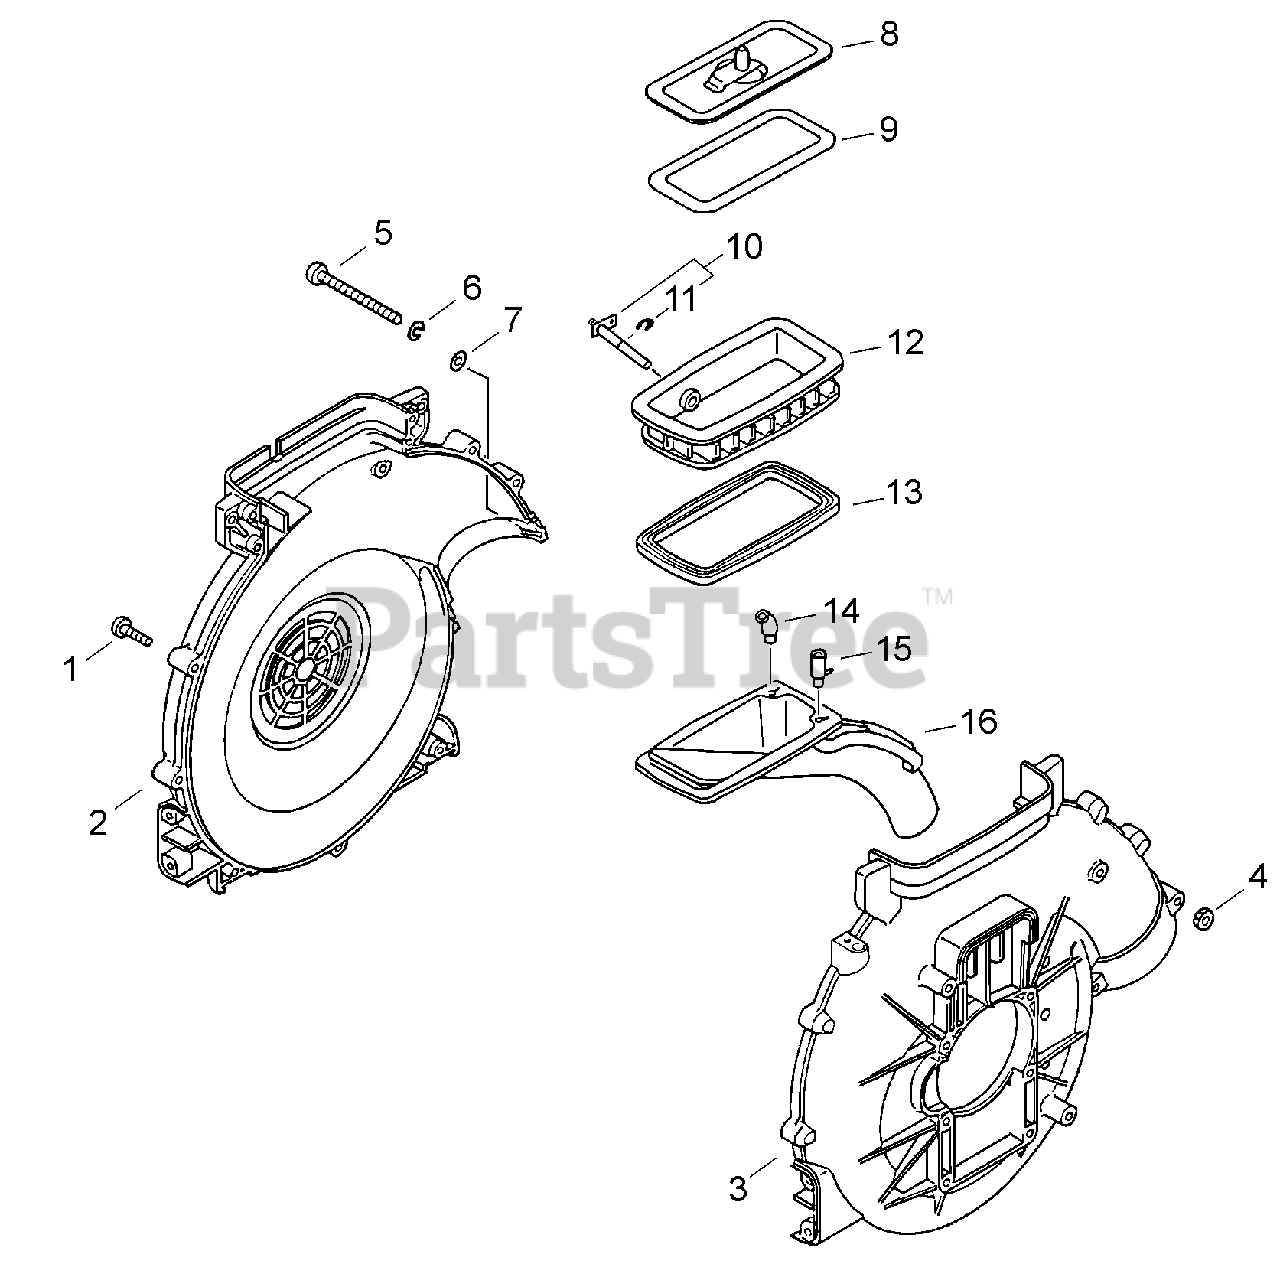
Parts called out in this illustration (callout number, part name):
1	SCREW 5×25 SUS
2	COVER, FAN
3	CASE, FAN
6	WASHER, SPRING 5 SUS
7	WASHER SS 5 MM
8	PLATE, BOTTOM
9	GASKET, SHUTTER
10	SHAFT ASSY, SHUTTER
11	E-RING 8 SUS
12	TANK, LOWER
13	GASKET, LOWER TANK
14	GUIDE, LOWER TANK AIR
15	GUIDE, AIR
16	PIPE, DUST OUTLET
